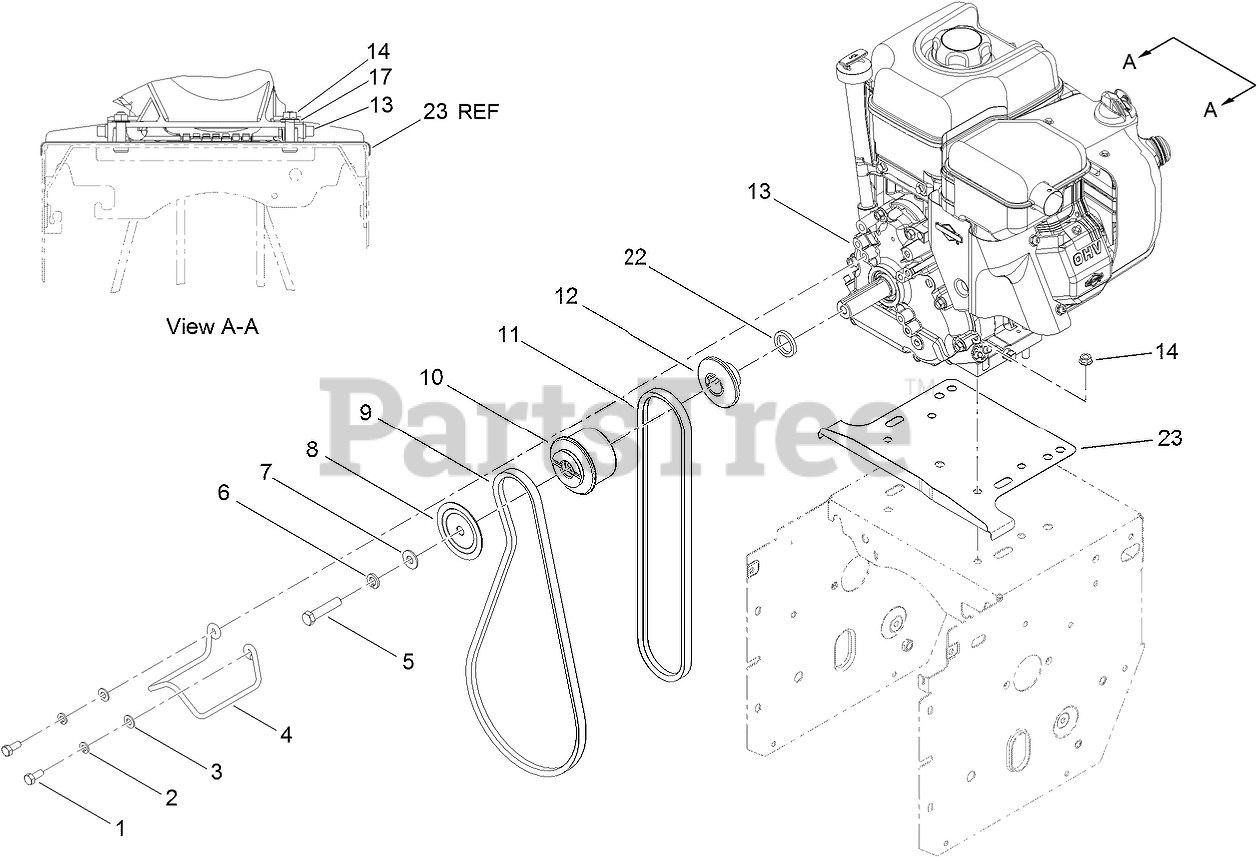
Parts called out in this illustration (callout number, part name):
1	SCREW-HH
2	WASHER-LOCK
3	WASHER-PLAIN
4	GUIDE-BELT
5	SCREW-HH
6	WASHER-LOCK
7	WASHER-FLAT
8	SHEAVE-HALF, IMPELLER
9	BELT-V
10	PULLEY-ENGINE, CENTER
11	V BELT-TRACTION
12	SHEAVE-HALF, TRACTION
14	NUT-HF
17	WASHER-FLAT
22	SPACER-HARDENED
23	SHIELD-DRIVE
